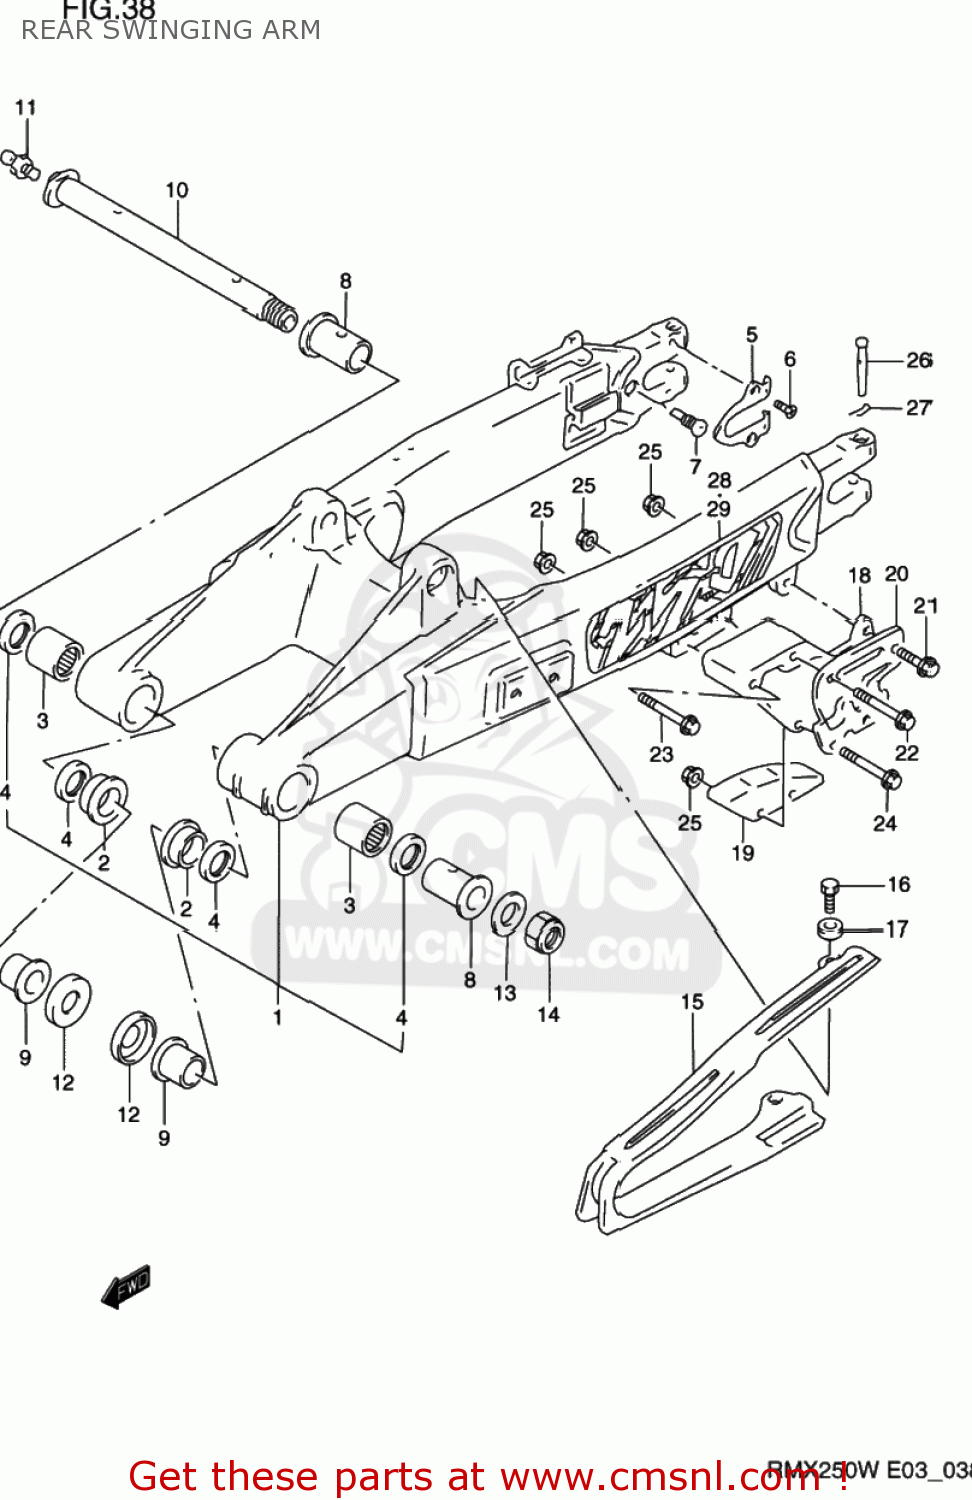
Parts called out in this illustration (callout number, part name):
1	SWING ARM ASSEMBLY,REAR
2	BUSHING,SWGARM PIVOT
3	BEARING(22X29X30)
4	SEAL,OIL(22X29X4)
5	PLATE,RR SWING ARM AXLE
6	SCREW(5X8)
7	SCREW (M10X21)
8	SPACER,RR SWGARM PIVOT
9	SPACER,SWGARM PIVOT INNER
10	SHAFT SET,SWING ARM
11	NIPPLE
12	COVER,SWINGINGARM PIVOT
13	WASHER, FIXED DRIVE FACE
14	NUT
15	BUFFER,CHAIN TOUCH DEFENSE
16	BOLT
17	WASHER
18	GUIDE,CHAIN
19	DEFENSE,CHAIN GUIDE
20	PLATE,CHAIN GUIDE OUTER
21	BOLT,G/S SWITC
22	BOLT
23	BOLT
24	BOLT
25	NUT
26	PIN
27	CLIP
28	EMBLEM,SWING ARM
29	EMBLEM,SWING ARM,LEFT
